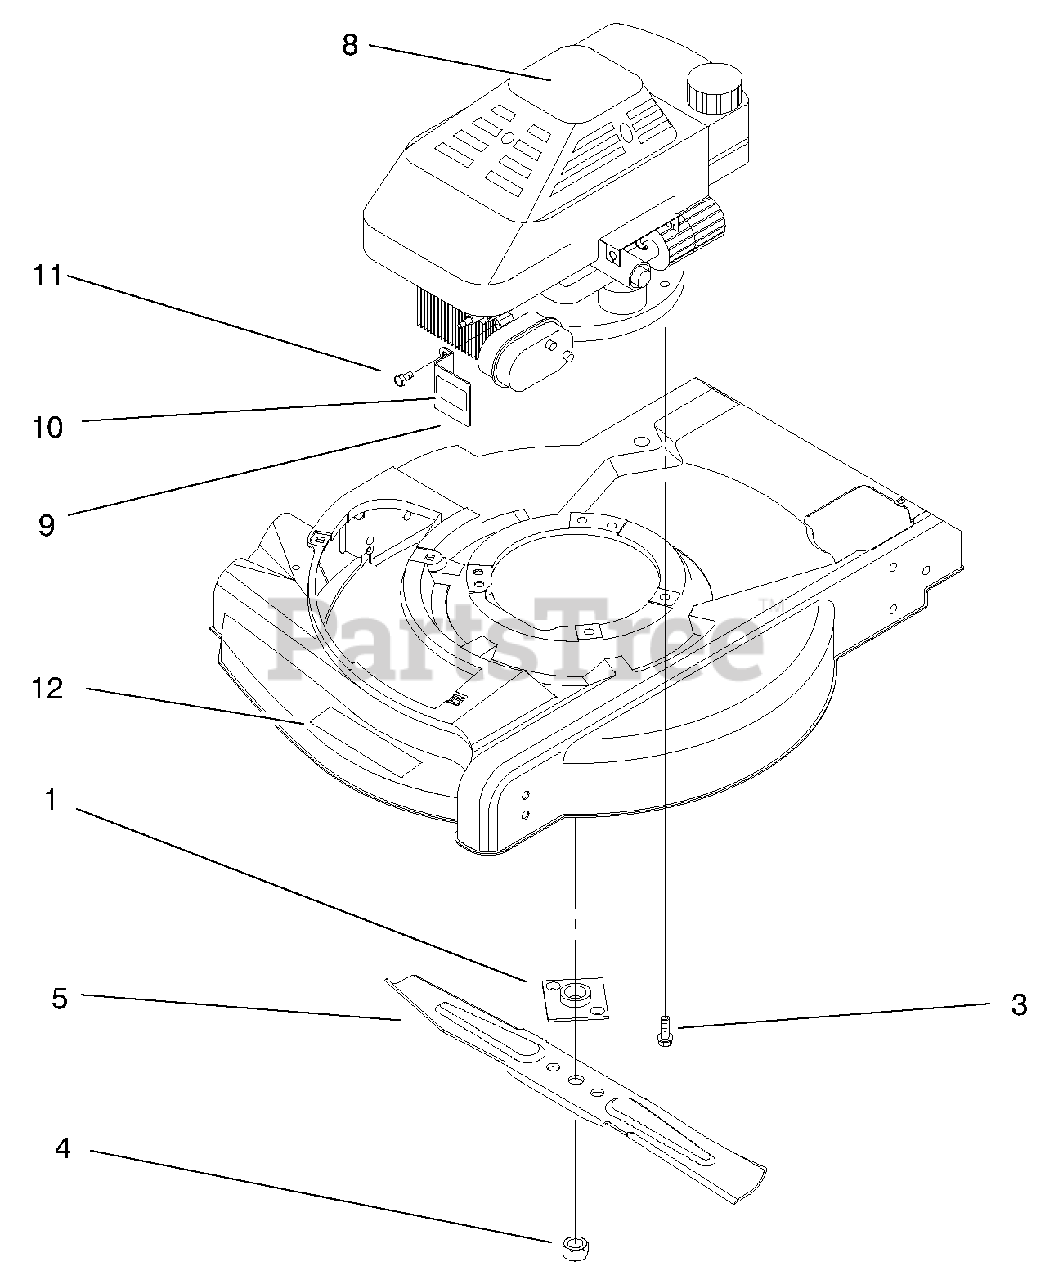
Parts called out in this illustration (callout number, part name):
1	Plate & Collar ASM
2	Screw-Taptite w/Patch
4	Nut-Blade
5	Blade-21" Whirl
8	Decal-Recoil
9	Guard-Muffler
10	Decal-Hot Surface
11	Screw-TAP
12	Decal-Deck
